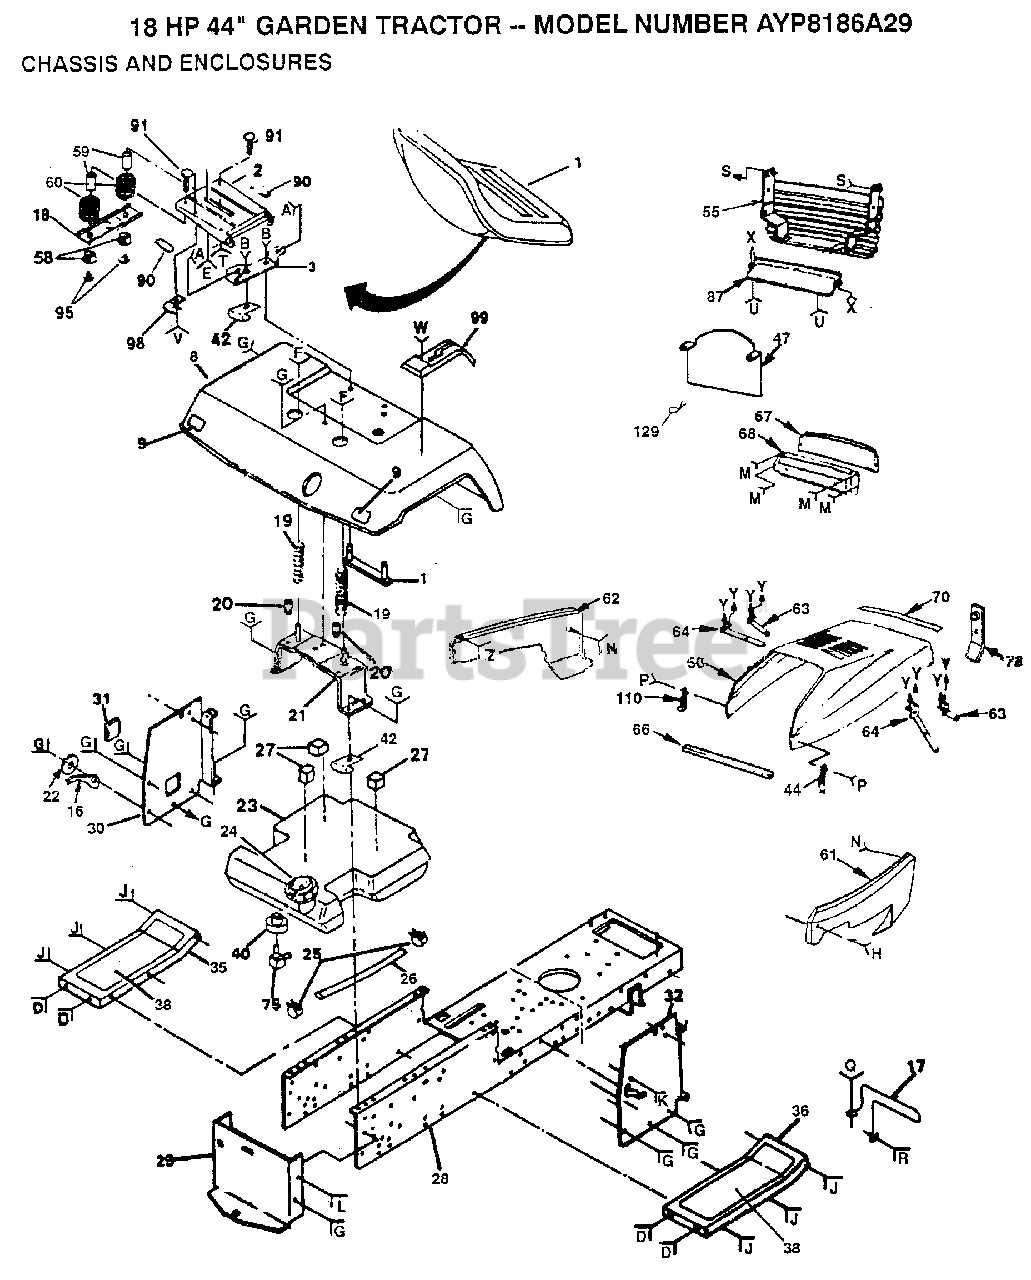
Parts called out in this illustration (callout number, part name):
8	FENDER
9	REFLECTOR-TAIL YT
17	GUARD MUFFLER HYT
18	BRKT SWITCH
19	SPRING COMPRESSIO
20	NUT-PUSH YT
22	WASHER T
25	HOSE CLAMP
26	FUEL LINE T
27	PAD-SPACER LT
28	CHASSIS
29	DRAW BAR
30	PANEL DASH LH
31	COVER ACCESS
32	DASH PANEL RH
38	FOOTREST PAD
40	BUSHING OUTLET T
42	CLIP T
47	BAFFLE HOOD VERT
58	BUSHING
59	SPACER SPLIT
60	SPRING COMPRESSED
66	FOAM-STRIP LT
67	LENS LT
75	FUEL TANK STEM GT
90	STRIP FORM
99	CONSOLE SHIFTER
110	HOOD LATCH T
